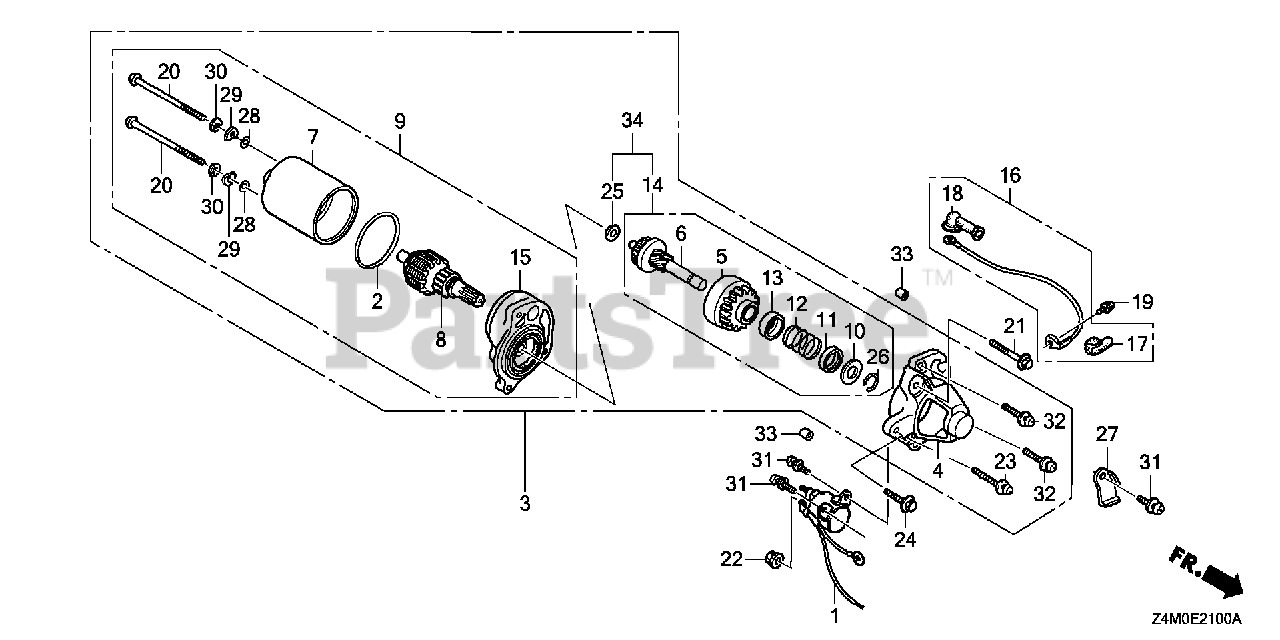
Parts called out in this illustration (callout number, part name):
1	SWITCH, STARTING MAGNET
3	STARTER MOTOR UNIT
4	COVER, GEAR
5	PINION ASSY.
6	SHAFT UNIT, GEAR
7	YOKE ASSY.
8	ROTOR ASSY.
9	MOTOR ONLY
10	PIECE A, STOPPER
11	PIECE B, STOPPER
12	SPRING, RETURN
13	COVER, SPRING
15	BRACKET, FR.
16	WIRE, MAGNETIC SWITCH
17	COVER, MAGNET SWITCH TERMINAL
18	COVER, STARTER MOTOR TERMINAL
19	SCREW, PAN (5X8)
20	BOLT, SETTING
21	BOLT, FLANGE (6X32)
22	NUT-WASHER (6MM)
23	SCREW-WASHER (5X30)
24	BOLT, FLANGE (6X25) Use up to Engine SN 2056819.
25	WASHER, PINION
26	CIRCLIP (10.2MM)
27	HOLDER, HARNESS
29	WASHER, SPECIAL
30	WASHER, SPRING
31	SCREW-WASHER (5X14)
32	SCREW-WASHER (5X20)
33	PIN A, DOWEL (8X10)
34	GEAR ASSY.
